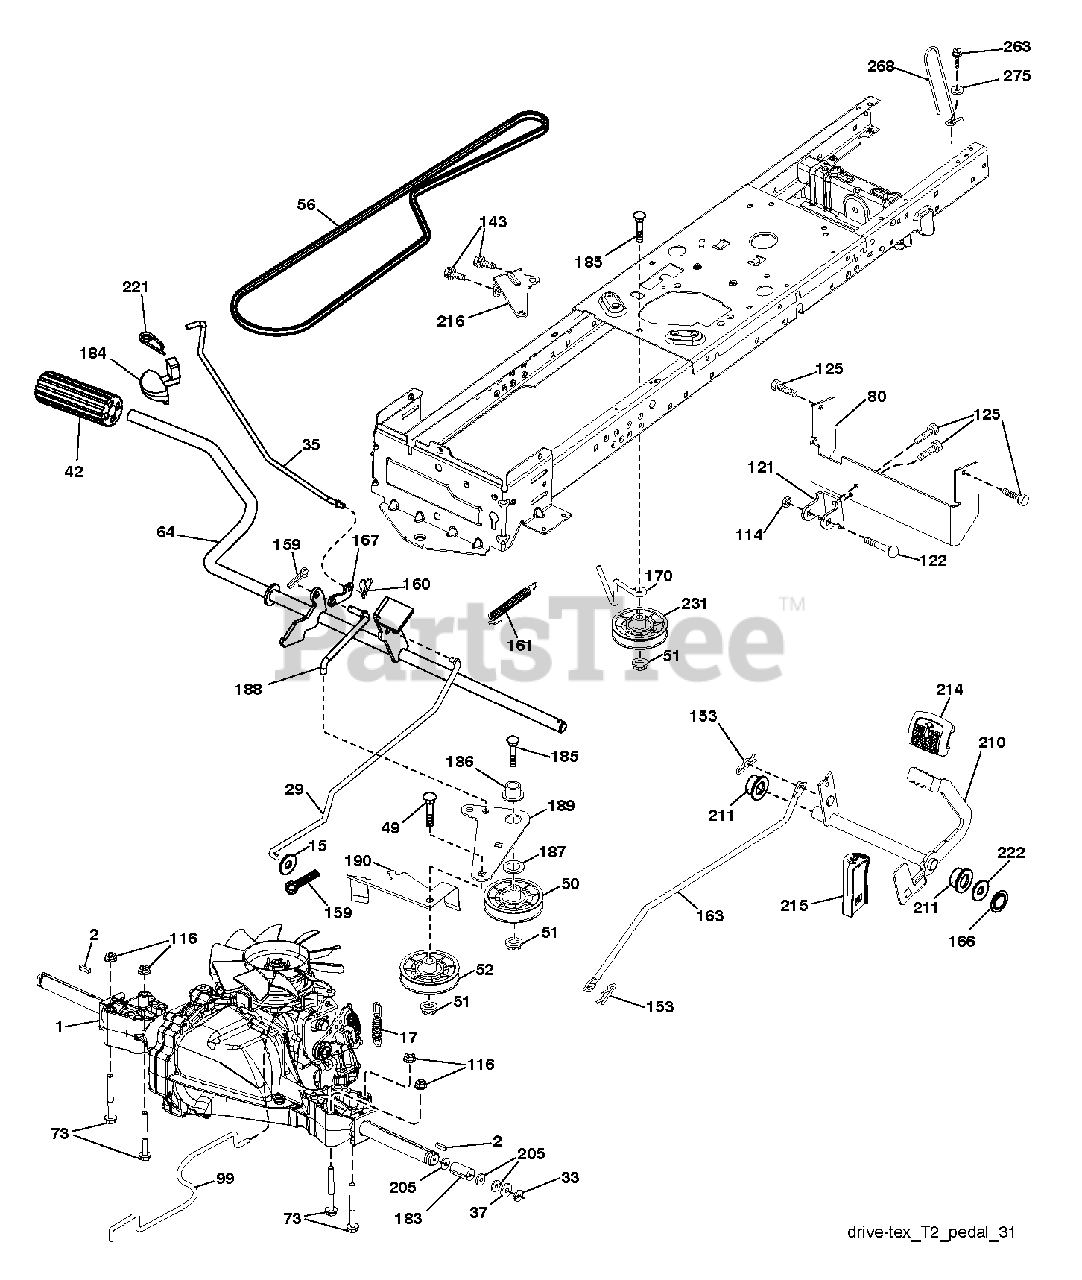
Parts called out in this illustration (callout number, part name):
2	SQUARE KEY
17	SPRING.BRAKE.HG3000/3500
29	ROD BRAKE
33	E-RING LT
35	ROD, BRAKE, PARK
42	PEDAL COVER T
49	BOLT
50	IDLER.FLAT.910.OFFSET
51	NUT LOCK FLG 3/8-16 UNC
52	IDLER.V-GROOVE.910.OFFSET
64	SHAFT.ASM.PEDAL.BRK.CNTR
73	BOLT HEX 5/16-18 GR 5
80	Strap.Torque.T2
99	ROD.ASM.BYPASS.SPRING.T2.FS
114	NUT.71038.31-18.HEX.NYLOCK
116	NUT LOCK HEX FLANGE 5/16-18
121	BRACKET STRAP TORQUE
122	BOLT.5/16-18X2.5
125	SCREW
143	SCREW LT
153	RETAINER M
159	COTTER PIN
160	RETAINER CLIP
161	SPRING, RETURN LT
163	ROD.CONTROL.PCH.T2.TEX
166	NUT.PUSH.625
167	LATCH.BRAKE.SPRING
170	KEEPER.CENTER SPAN.1.688
183	SPACER, AXLE PVST
184	Parking Brake Handle
186	SPACER.RETAINER
187	WASHER 12/32X2X10GA
188	LINK.CLUTCH.GROUND.DRIVE
189	BELLCRANK.GROUND.DRIVE.TEX.
190	KEEPER.BELLCRANK.DRIVE
210	ROCKER.ASM.PEDAL.CONTR
211	BEARING.NYLON
214	PAD PEDAL FORWARD
216	BRACKET.PULLEY.IDLER.W/TEX
221	RETAINER.SPRING.CLIP.H
222	WASHER 21/32 X 1-1/4 X 10 GA.
231	IDLER.V-GROOVE.1.688.OFFSET
263	SCREW, 3/8-16X3/4
275	WASHER
